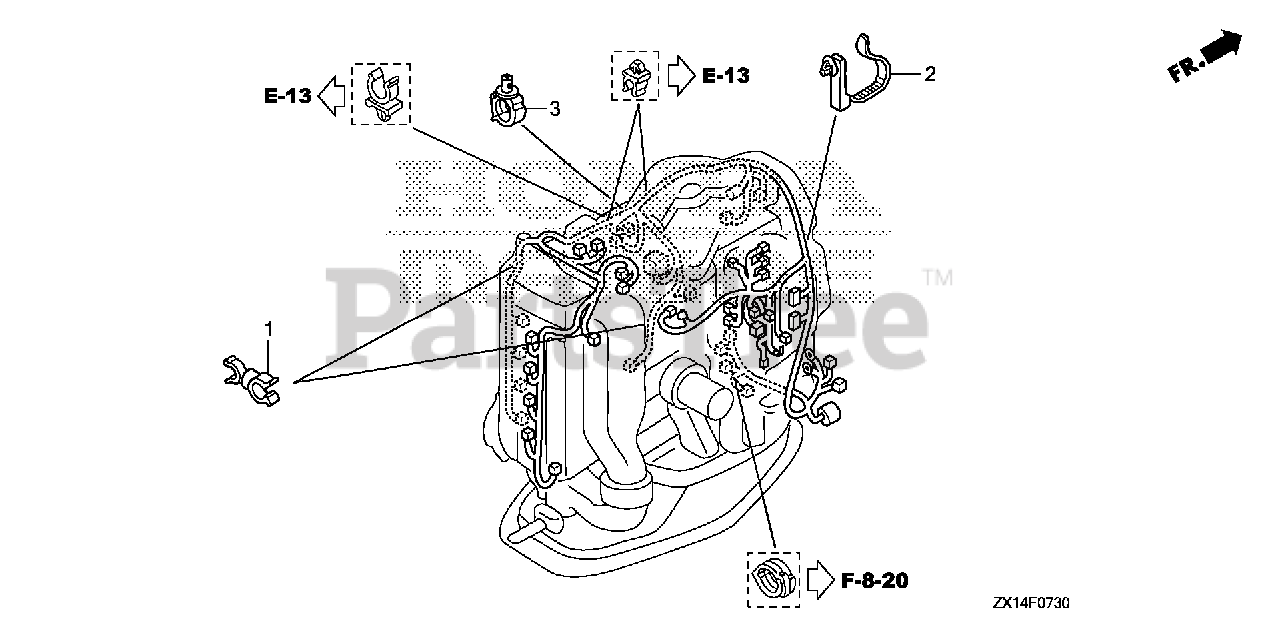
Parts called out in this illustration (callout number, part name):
1	CLAMP, HOSE
2	BAND, HARNESS OFFSET (10) (122.5MM) (BROWN)
3	CLAMP, ENGINE SUB-WIRE
